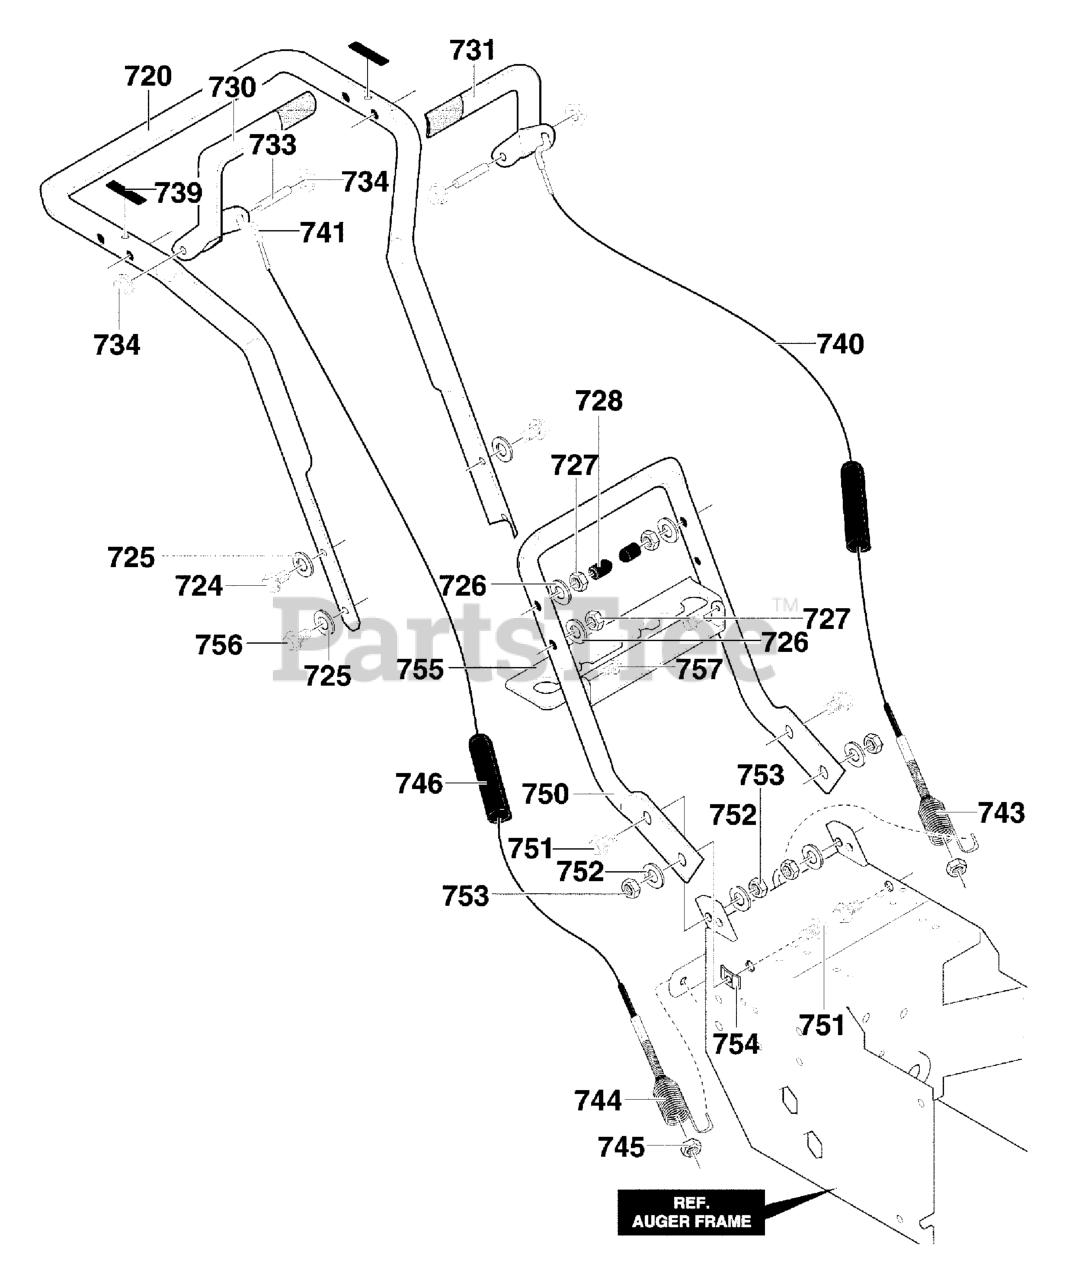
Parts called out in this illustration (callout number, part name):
720	HANDLE, UPPER
724	SCREW, 5/16-18 x 2.75
725	WASHER, FLAT .349X.69X.066
726	WASHER, SPTLK .31X.58X.08
727	NUT, 5/16-18 REGHEX
728	STOP, RED PLASTIC
730	CLUTCH HANDLE RH
731	CLUTCH HANDLE LH
733	PIN, CLUTCH HANDLE
734	NUT, PUSH ON CAP
739	BUMPER, RECTANGLE
740	CABLE, CLUTCH 28.44L
741	CABLE, AUGER CLUTCH
743	TENSION SPRING
744	SPRING, AUGER CLUTCH
745	NUT, 1/4-20
746	BOOT, CLUTCH SPRING
750	HANDLE, LOWER
751	CAPSCREW, Hex Head, 5/16-18 x 1
752	WASHER, SPTLK
753	NUT, 5/16-18 REGHEX
754	PUSHNUT, 5/16 BOLT RETAINER
755	BRKT, GEAR SELECTOR
756	SCREW, 5/16-18 x 2.00
757	SCREW, .25X.75X.51
